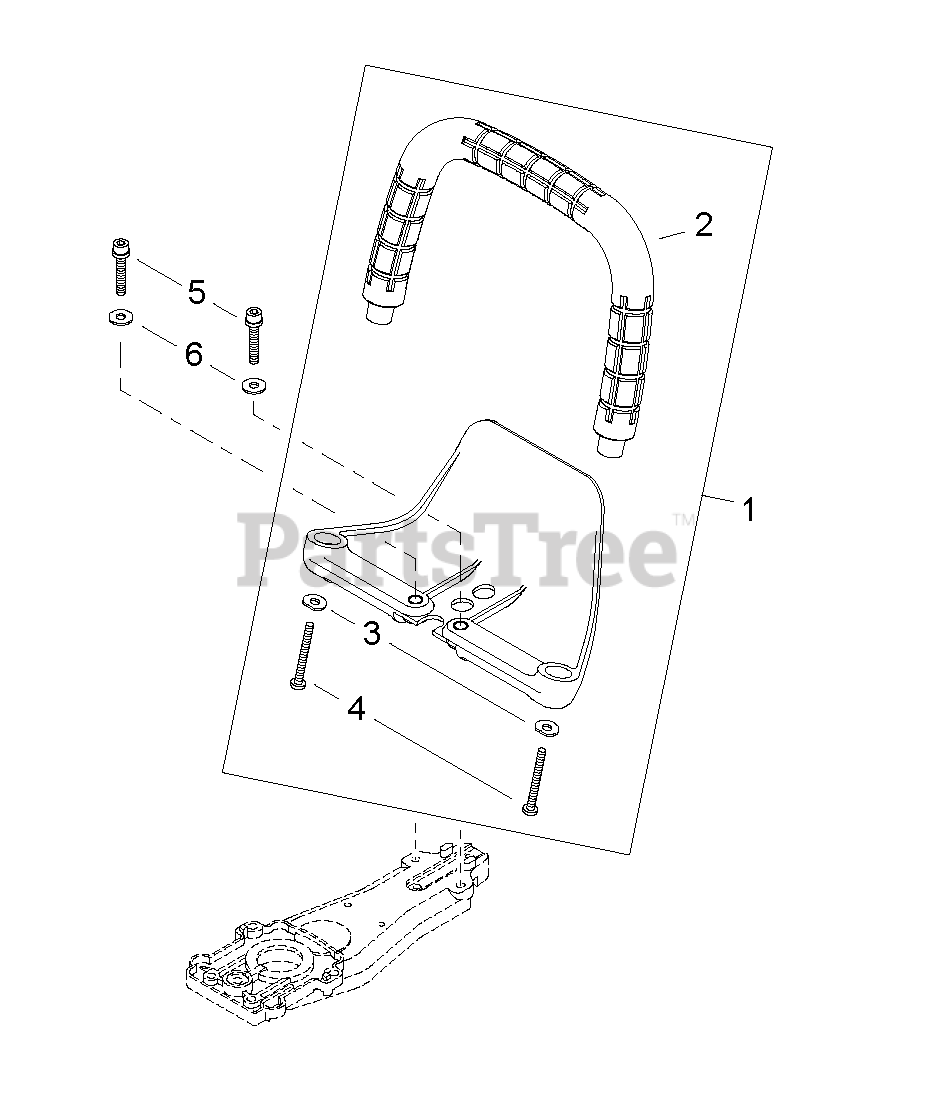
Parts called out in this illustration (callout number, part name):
1	HANDLE ASSY - FRONT
2	HANDLE - FRONT
3	WASHER
4	SCREW - 5 -- TAPPING
5	SCREW - 6X30
6	WASHER - 16
